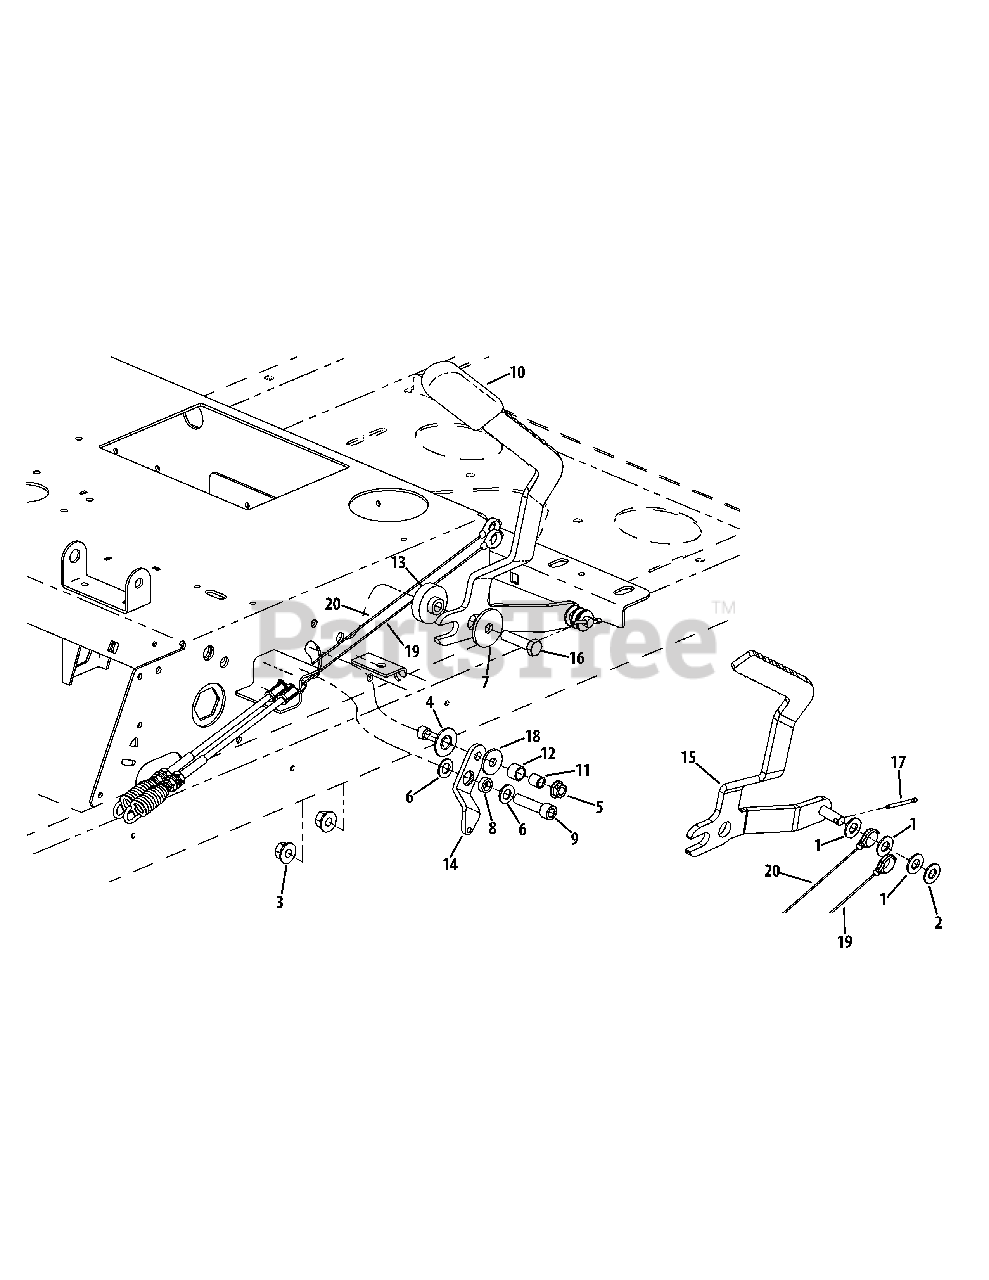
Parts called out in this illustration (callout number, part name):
1	Flat Washer, .406 x .812 x .062
2	Flat Washer, 3/8
3	Hex Nut, 3/8-16 Flange Lock
4	Flat Washer, .570 x 1.12 x .062
5	Flange Lock Nut, 5/16-18
6	Washer, .375 x .738 x .063
7	Flat Washer, .390 x 1.5 x .134
8	Spacer, .380 x .563 x .196
9	Sockethead Capscrew, 3/8-16 x 1.50
10	Parking Brake Grip
11	Spacer, .322 x .438 x .44
12	Spacer, .442 x .563 x .405
13	Step Hub, .379 x 1.5 x .257/.400
14	Lockout Lever Plate
15	Brake Handle
16	Hex Head Cap Screw, 3/8-16 x 1.50
17	Cotter Pin, 1/8 x .75
18	Washer, .345 x 1.00 x .100
19	Left Hand Brake Cable
20	Right Hand Brake Cable
